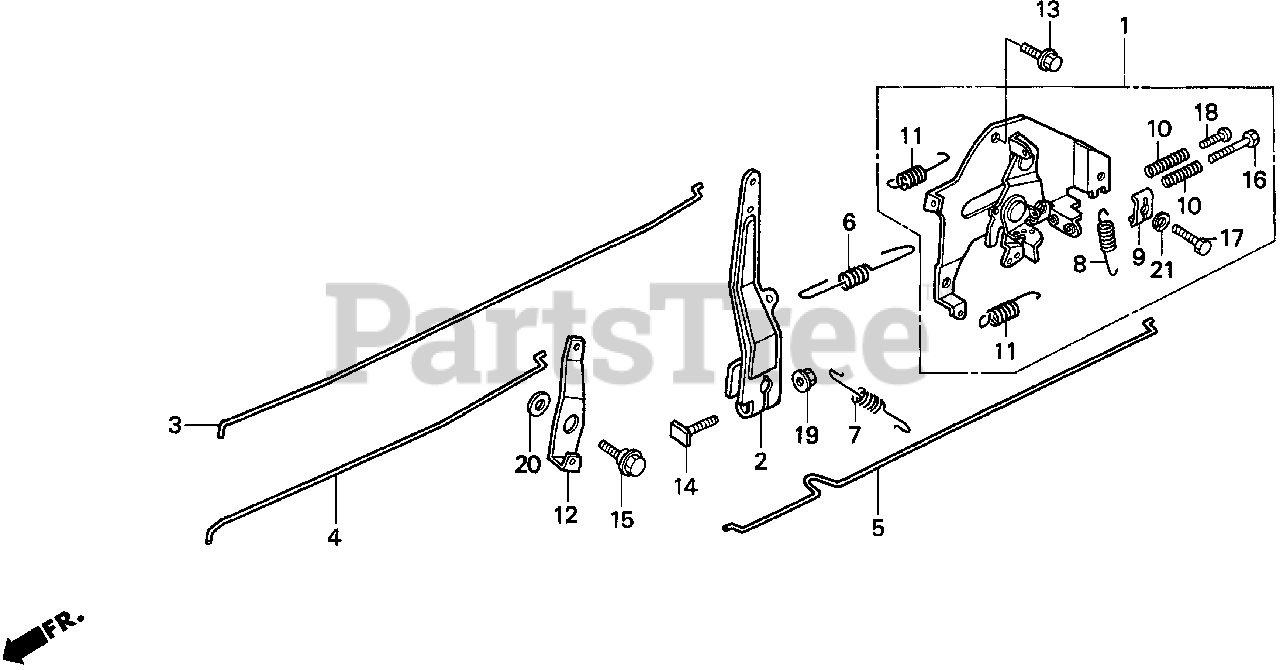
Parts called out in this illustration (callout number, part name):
1	CONTROL ASSY.
2	ARM, GOVERNOR
3	ROD, GOVERNOR
4	ROD, CHOKE
5	ROD, JOINT
6	SPRING, GOVERNOR
7	SPRING, GOVERNOR PRIMARY
8	SPRING, LEVER
9	HOLDER, CABLE
10	SPRING, CONTROL ADJUSTING Use from Engine SN 2327377.
11	SPRING, CABLE RETURN
12	LEVER, CHOKE JOINT
13	BOLT, FLANGE (6X12) (CT200)
14	BOLT, GOVERNOR ARM
15	BOLT, FLANGE (6MM)
16	BOLT, RECESSED (5X34)
17	BOLT, RECESSED (5X16)
18	SCREW, PAN (5X20)
19	NUT, FLANGE (6MM)
20	WASHER, PLAIN (6MM)
21	WASHER, SPRING (5MM)
